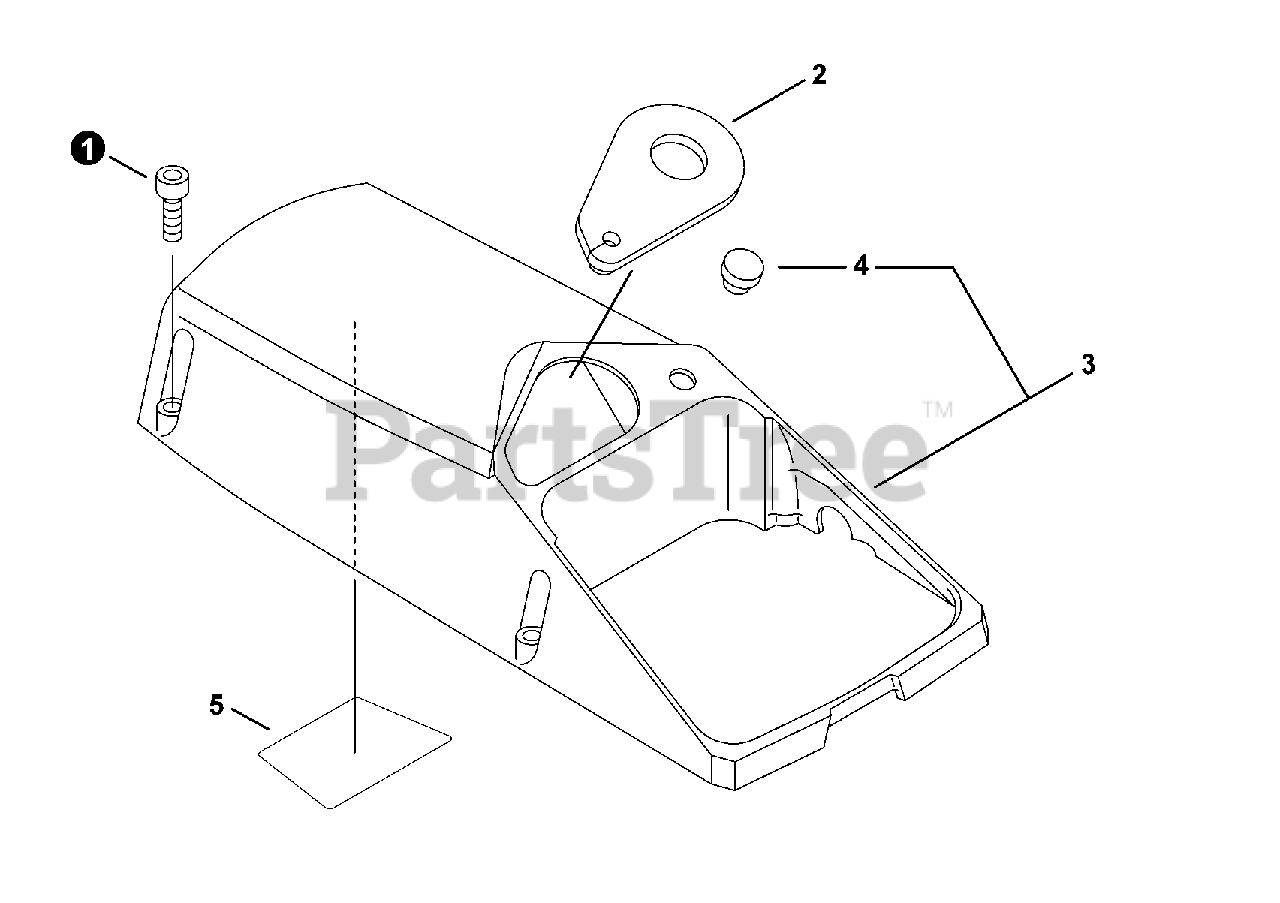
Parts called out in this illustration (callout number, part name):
1	BOLT 5×20
2	PLATE, GUIDE
3	ENGINE COVER KIT - ORANGE
5	SHIELD, HEAT
